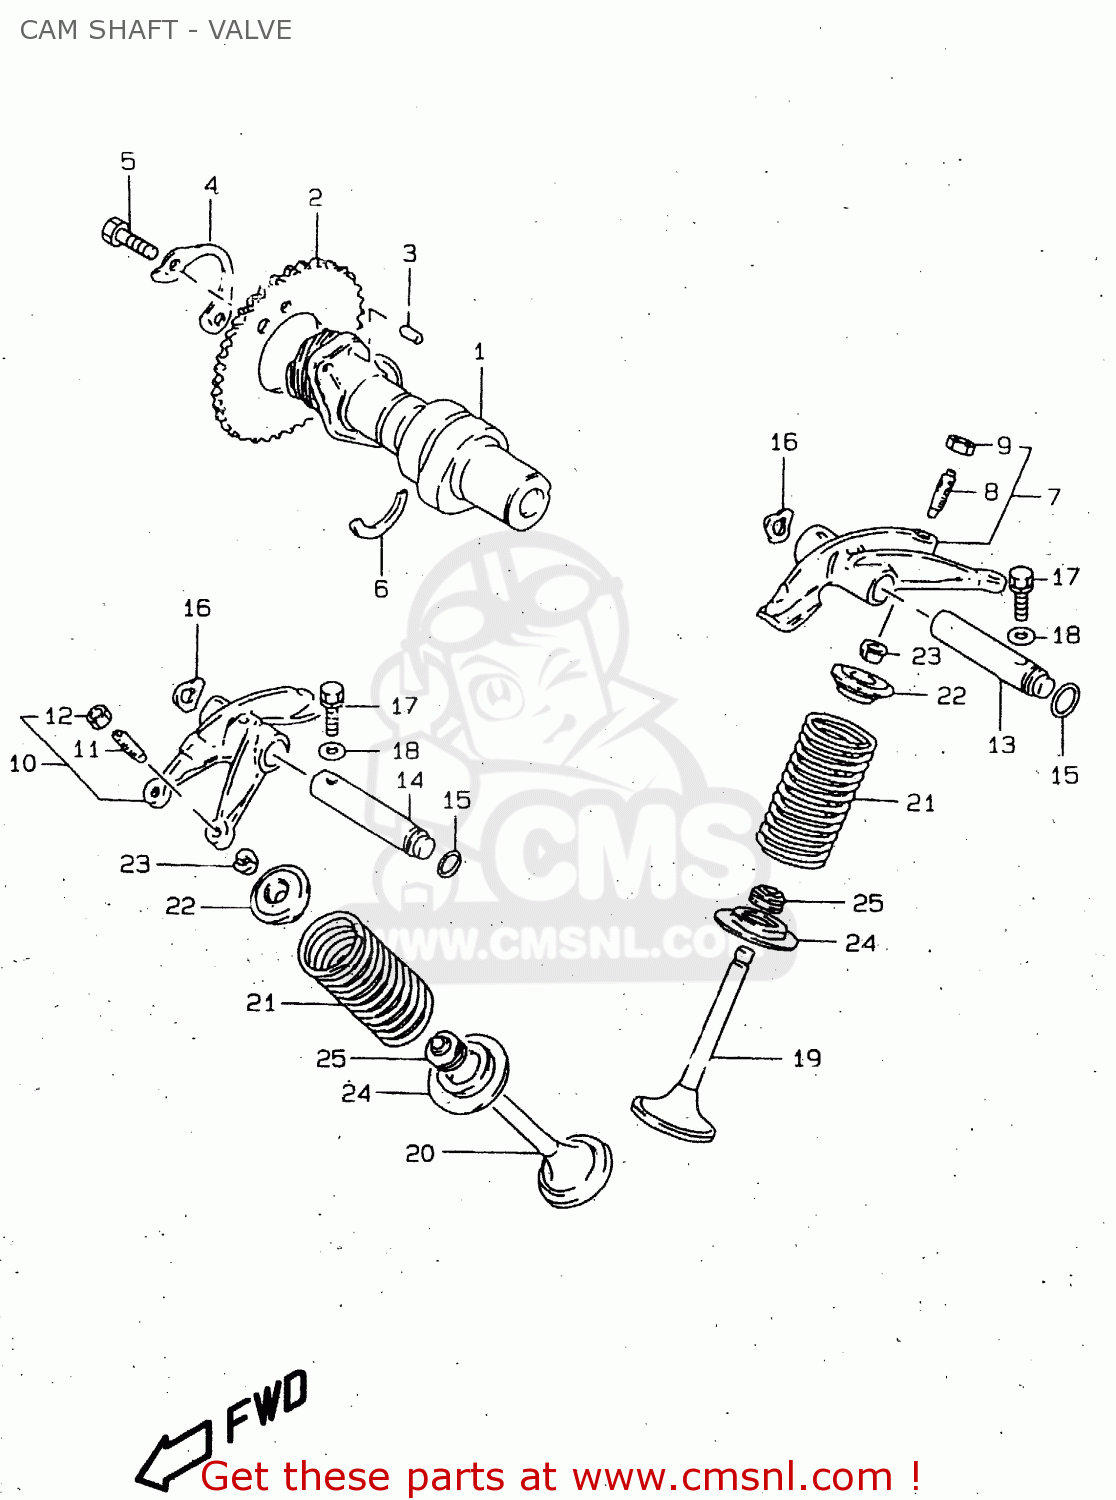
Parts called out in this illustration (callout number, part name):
1	CAMSHAFT
2	SPROCKET,CAMSHAFT(NT:42)
3	PIN
4	WASHER,CAM CHAIN SPROCKET
5	BOLT(6X12.5)
6	C RING
7	ARM,VALVE ROCKER INTAKE
8	SCREW,TAPPET ADJUSTING
9	NUT,TAPPET ADJUSTING
10	ARM,VALVE ROCKER EXHAUST
11	SCREW,TAPPET ADJUSTING
12	NUT,TAPPET ADJUSTING
13	SHAFT,VLV ROCKER ARM IN(L:91.5
14	SHAFT,VLV ROCKER ARM EXH(L:76)
15	O RING(D:1.9,ID:8.6)
16	WASHER
17	BOLT
18	GASKET(5.8X13X1.2) (NAS)
19	VALVE,INTAKE
20	VALVE,EXHAUST
21	SPRING,VALVE
22	RETAINER,VALVE SPRING
23	COTTER VALVE
24	SEAT,VALVE SPRING
25	SEAL,OIL(5.5X11X8.2)
